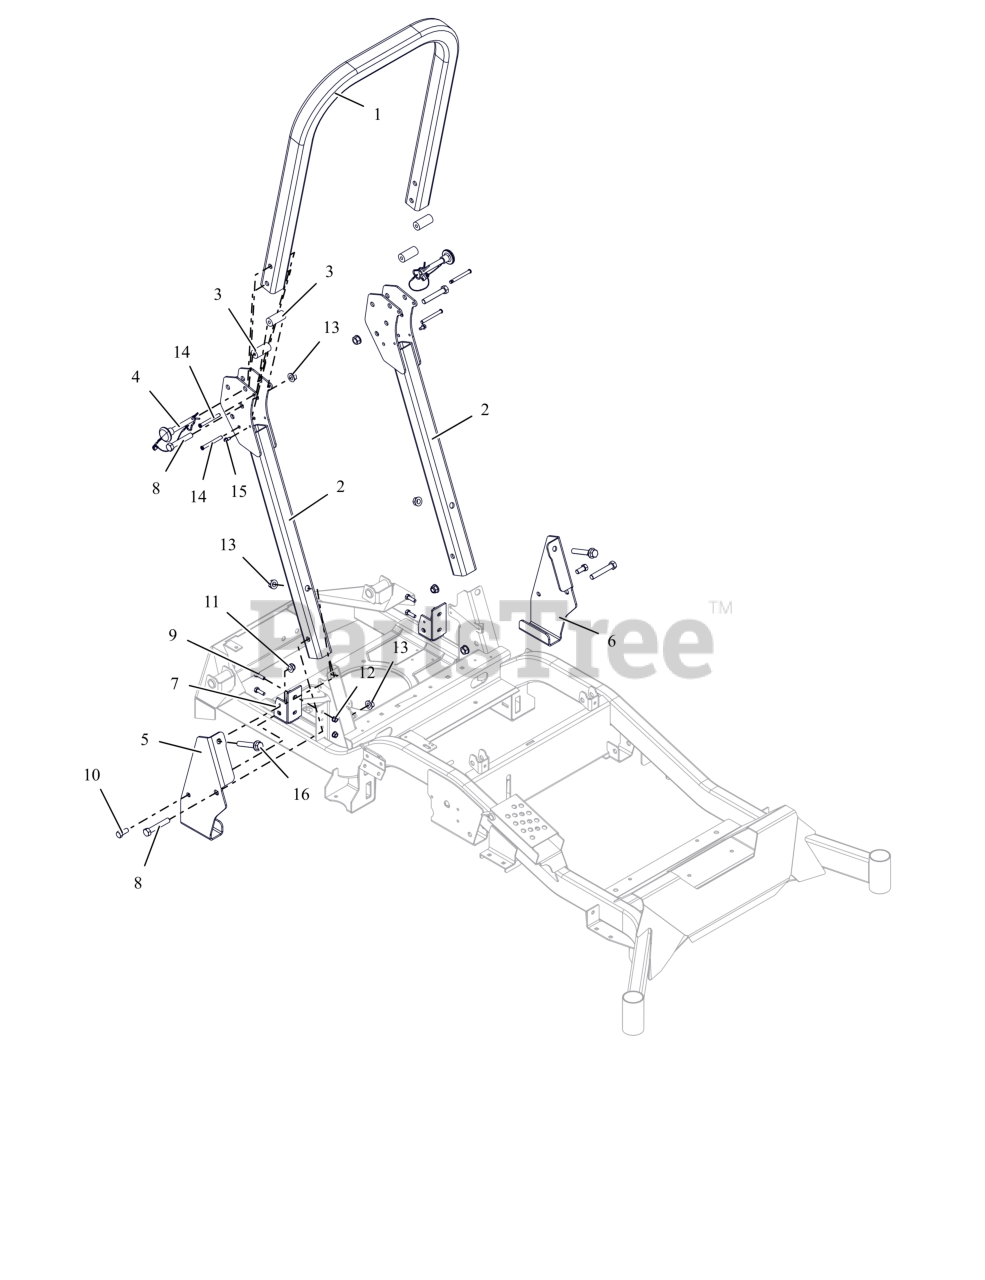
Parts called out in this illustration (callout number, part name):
1	HOOP- ROPS (TALL)
2	ROPS,PROTURN Z REPLACEMENT-TALL
3	BUMPER, ROPS ANTI-VIBRATION
4	PIN, ROPS W/LANYARD
5	BRKT, ROPS SUPPORT - RH
6	BRKT, ROPS SUPPORT -LH
7	BRKT, ROPS SUPPORT (BLACK)
8	BLT, HEX .50-13X3.00 G5 ZCC
9	BLT, HEX .31-18X1.00 G8 ZCC
10	BLT, HEX .44-14X1.00 G5 ZCC
11	NUT, LK-NYL-FLG .44-14 GR5 ZC120
12	NUT,LK-CTR-FLG .31-18 GF ZCC
13	NUT-LK-CTR-FLG .500-13 GG ZCC
14	PIN, SLIC .312 X 2.57
15	SCR-TAP .25-20X.50 HWH ZCC
16	BLT- HEX-FLG .50-13X3.00 G5 ZC
